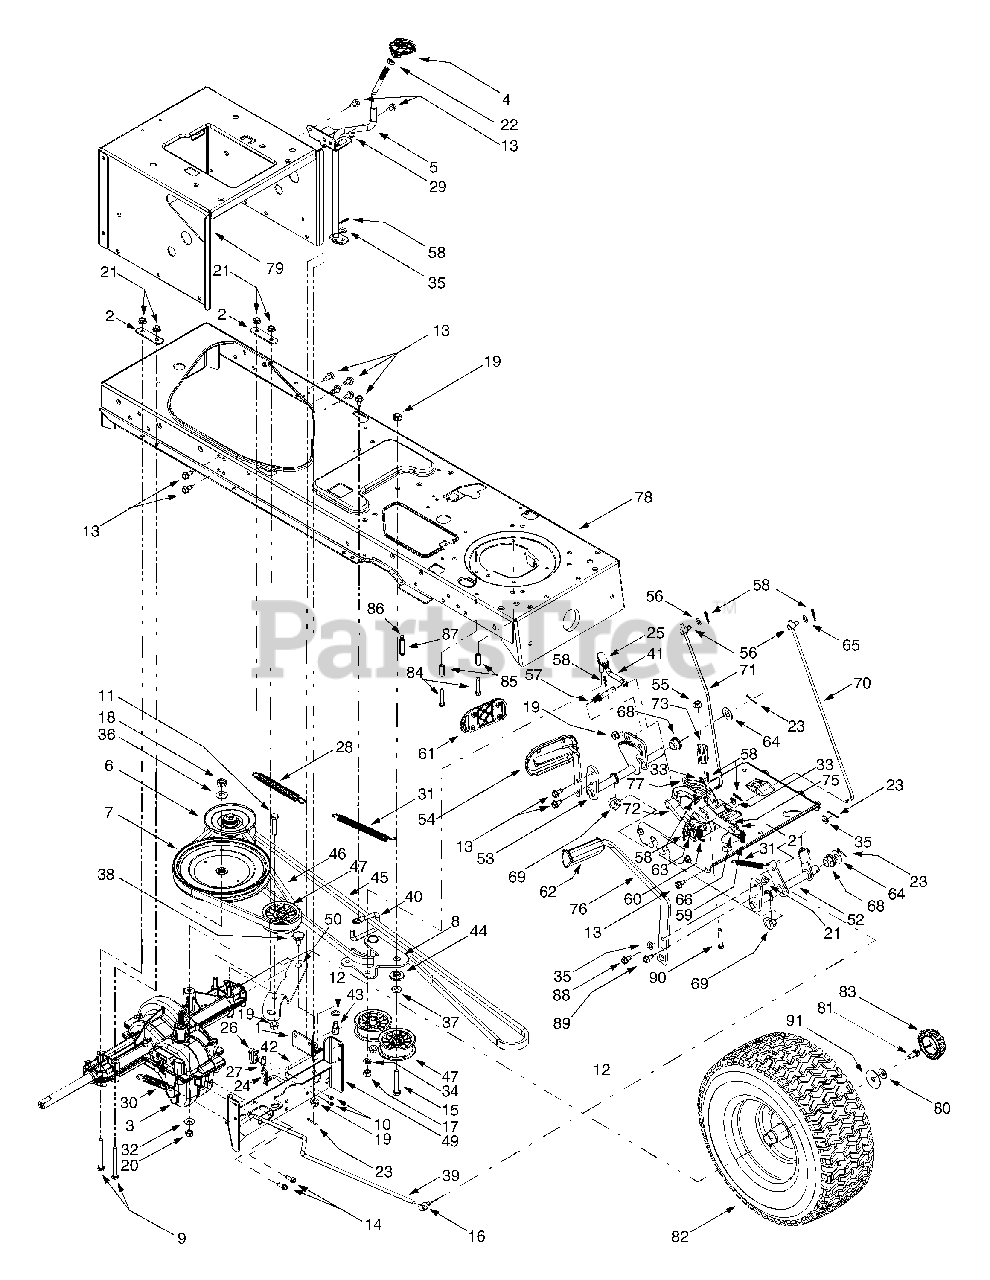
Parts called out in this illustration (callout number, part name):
3	Single-speed Transmission Assembly
4	Shifter Knob
5	Shift Lever
6	Variable-speed Pulley Assembly
7	Transmission Pulley, 8.5 x .5-36
8	Double-idler Bracket
9	Hex Cap Screw, 5/16-18 x 3
10	Self-tapping Screw, #8-18 x .5
11	Hex Cap Screw, 3/8-16 x 1.75
12	Flat Washer, .51 x 1.0 x .060
13	Self-tapping Screw, 5/16-18 x .625
14	Self-tapping Screw, 1/4-20 x .75
15	Hex Cap Screw, 3/8-16 x 2.25
16	Ferrule, 5/16-18
17	Hex Nut, 3/8-24
18	Hex Nut, 7/16-20
19	Flange Lock Nut, 3/8-16
20	Hex Nut, 3/8-16
21	Flange Lock Nut, 5/16-18
22	Jam Nut, 3/8-16
23	Cotter Pin
24	Internal Cotter Pin
25	Ball Joint
26	Short Spring Switch
27	Insulator Nut Plate
28	Extension Spring, .62 Dia. x 6.12
29	Compression Spring Clip
30	Extension Spring, .59 OD x 4
31	Extension Spring, .50 Dia. x 6.37
32	Bell Washer, .401 x .87 x .063
33	Flat Washer, .385 x .62 x .063
34	Lock Washer, 3/8
35	Flat Washer, 5/16
36	Bell Washer, .45 x 1.0 x .602
37	Flat Washer, .407 x .812 x .135
38	Shoulder Screw, .625 x .217
39	Brake Rod
40	Belt Guard
41	Idler Adjustment Rod, 3/8
42	Shift Rod
43	Adjustment Ferrule, 1/4-20 x 1.0
44	Shoulder Spacer, .38 ID
45	Variable-speed Belt
46	Drive Belt
47	Flat Idler, 2.75 OD
51	Adjustable Shift Bracket
52	Brake Control Assembly
53	Speed Control Assembly
54	Auto Drive(TM) Pedal Assembly
55	Flange Lock Nut, 3/8-16
56	Ferrule, 1/4-20
57	Pin, 3/8-16 x 2.43
58	Cotter Pin
59	Compression Spring, .34 OD x 1.0
60	Extension Spring, .50 OD x 1.41
61	Auto Drive(TM) Pedal Pad
62	Brake Pedal Pad
63	Flat Washer, .281 x .5 x .0625
64	Flat Washer, .64 x 1.24 x .06
65	Flat Washer, .344 x .062 x .03
66	Shoulder Screw, .437 x 1.62
67	Shoulder Screw, .5 x .434
68	Hex Flange Bearing
69	Split Hex Flange Bearing
70	Cruise Control Rod
71	Brake Lock Control Rod
72	Cruise Latch
73	Spacer, 5/16 x 1.54
74	Stearing Support Bracket
75	Auto Drive(TM) Lockout Bracket
81	Hex Cap Screw, 5/16-24 x .75
83	Hub Cap
84	Self-tapping Screw, 1/4-20 x 1.5
85	Spacer
86	Self-tapping Screw, 1/4-20 x 1.75
87	Spacer
88	Self-tapping Screw, 5/16-18 x .75
89	Self-tapping Screw, 5/16-18 x .875
90	Hex Cap Screw, 3/8-16 x 2.5
91	Flat Washer, .350 x 1.59 x .062
